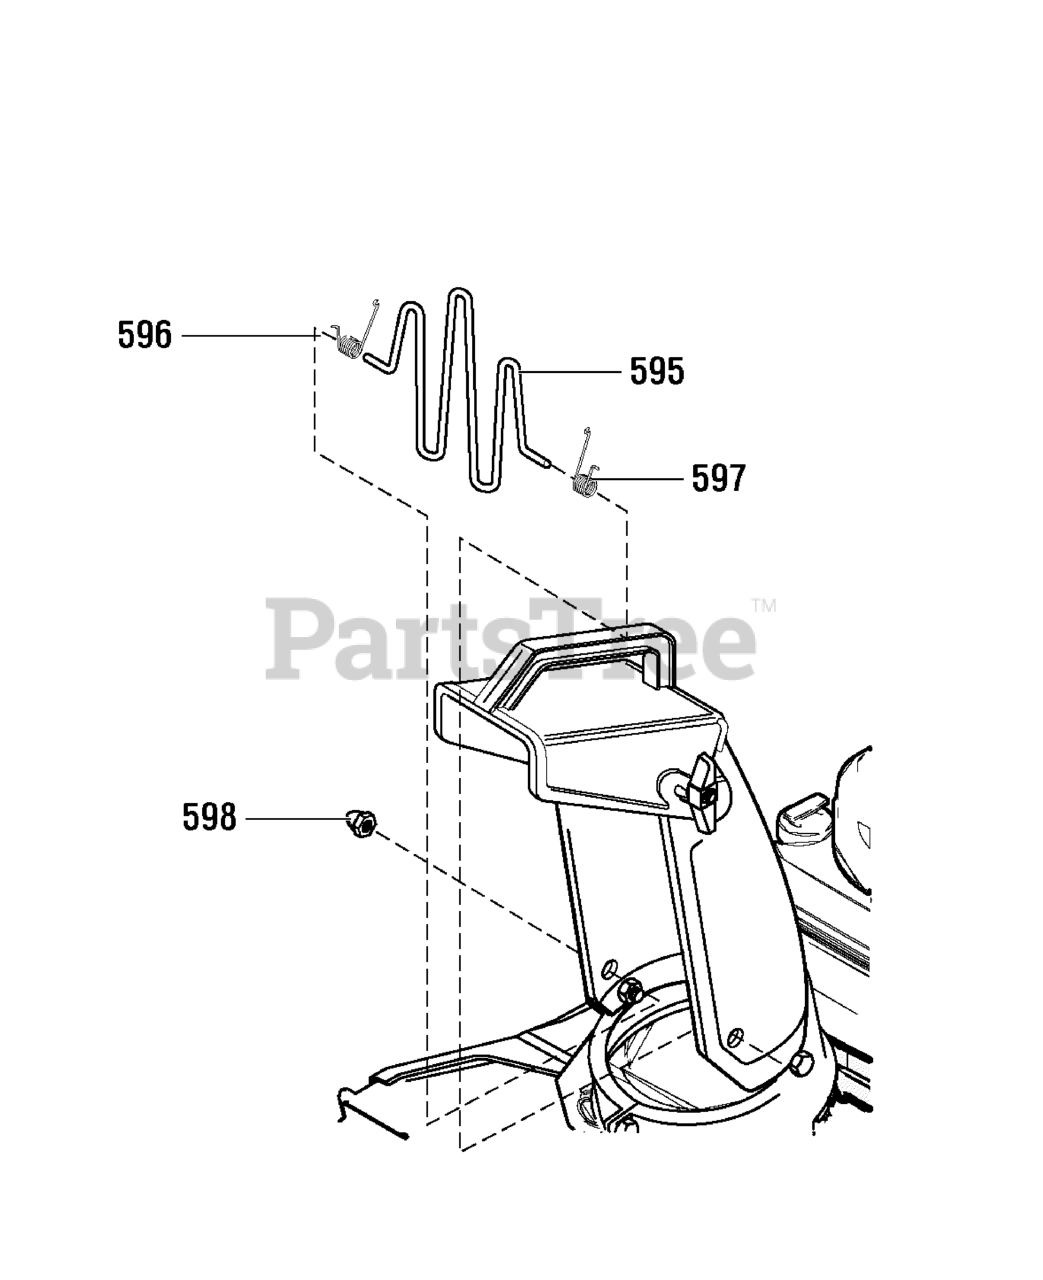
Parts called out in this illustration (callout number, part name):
595	GUARD, WIRE CHUTE LOWER
596	SPRING, TORSION CHUTE
597	SPRING, TORSION CHUTE
598	NUT, ACORN
